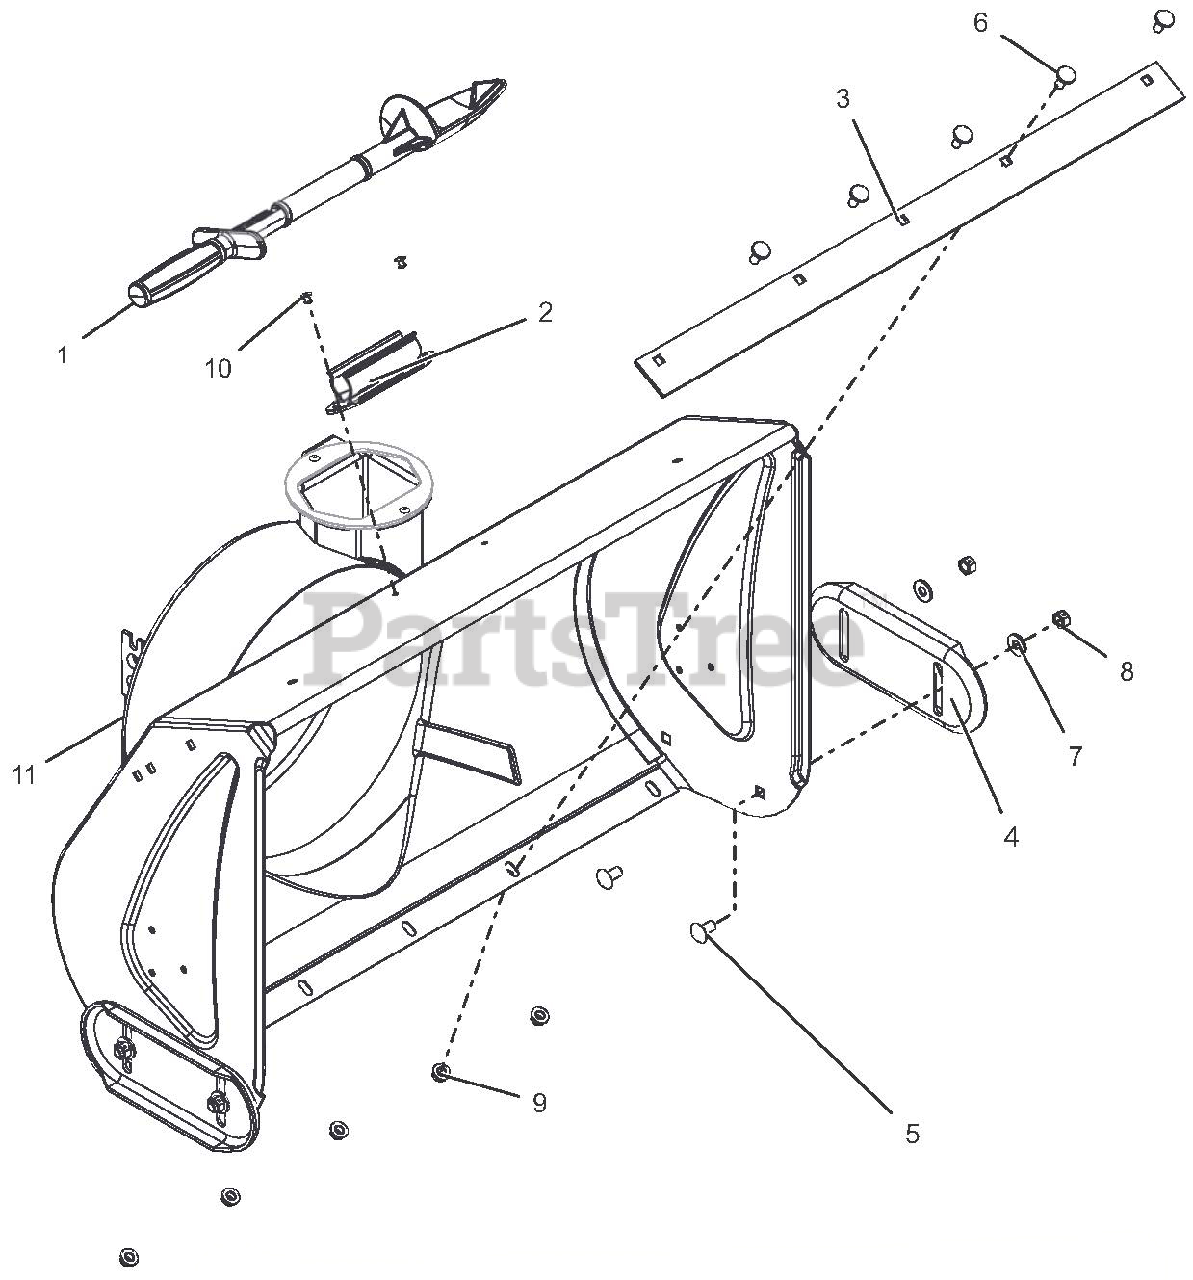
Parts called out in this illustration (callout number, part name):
1	DEVICE, SNOW CLEAN OUT
2	MOUNT, SNOW CLEAN OUT
3	SCRAPER BLADE, 28" COMPACT HI
4	SKID SHOE, REVERSIBLE
5	@BLT-RHDSSQNK .38-16X.75 G5YZ
6	BOLT, MODIFIED HEAD CARRIAGE
7	@WSHR-FL-STL.38X.875X.083 YWZC
8	@NUT-LK-CTR .38-16 YWZC
9	@NUT-LK-TOP-FLG .31-18 YWZC
10	RVT-POP .187 YZ
11	BLOWER HOUSING, 28"
